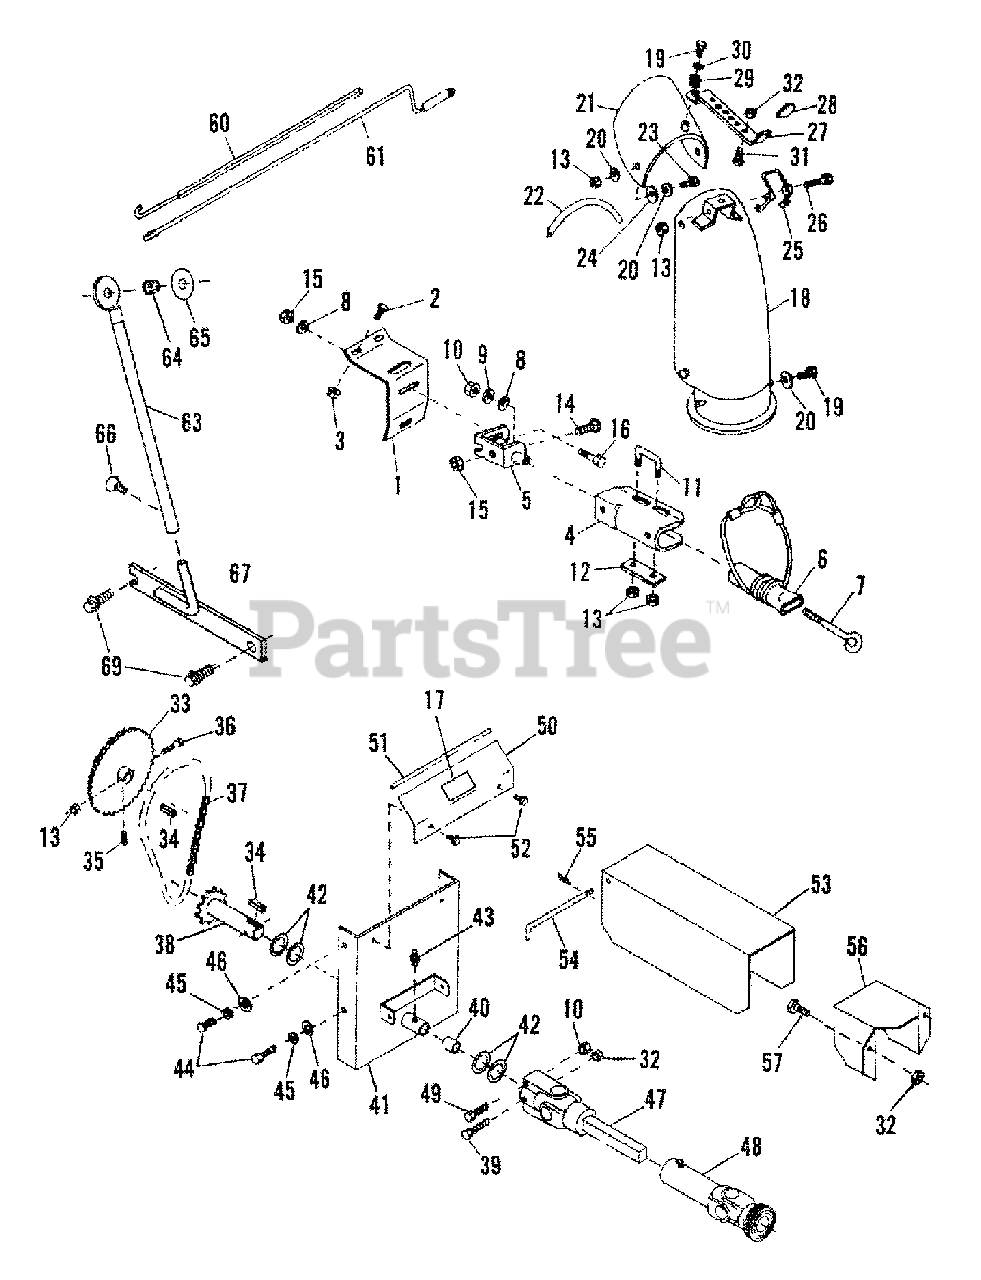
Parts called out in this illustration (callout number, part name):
1	Stack Drive Support Brkt
2	Bolt-Carriage, 5/16-18 x 3/4
3	Nut-Flg lock, 5/16-18
4	Stack Drive Shroud
5	Bracket and Tube Assy
6	Cable, Tube, & Sleeve Assy
7	Eye Bolt
8	Washer - Flat, 7/16
9	Spring Washer 3/8
10	Nut - Lock, 3/8-16
11	Level Wind "U" Bolt
12	Friction Strap
13	Nut-Lock, 3/8-16
14	Bolt - Carriage, 3/8-16 x 3/4
15	Nut - Top Lock - Hex, 3/8-16
16	Bolt - Carriage, 3/8-16 x 1
17	Decal - Warning
18	Elbow
19	Bolt - Hex Hd., 1/4-20 x 1/2
20	Washer - Flat, 1/4
21	Deflector & Decal Assy
22	Seal Trim
23	Bolt - Hex Hd, 1/4-20 x 3/4
24	Washer - Flat, 3/8
25	Deflector Lock Spring
26	Bolt - Hex Hd, 1/4-20 x 1-3/4
27	Deflector Lock Strap
28	Rubber Handle Grip
29	Rubber Grommet
30	Washer - Flat, 1/4
31	Bolt - Hex Hd 3/8-16 x 3/4
32	Nut - Top Lock, 5/16-18
33	Sprocket and Hub Assy
34	Key - Square, 1/4 x 1
35	Setscrew - Sq. Hd, 5/16-18 x 1/2
36	Bolt - Hex Hd, 1/4-20 x 2
37	Drive Chain
38	Jackshaft Assy
39	Bolt - Hex Hd, 5/16-18 x 2
40	Roller Bearing
41	Jackshaft Housing Assy
42	Washer - Flat
43	Grease Fitting
44	Bolt - Hex Hd, 3/8-16 x 1
45	Washer - Lock, 3/8
46	Flat Washer, 3/8
47	PTO Shaft Assy - Male
48	PTO Shaft Assy - Quick disc.
49	Bolt - Hex Hd, 3/8-16 x 1-3/4
50	Chain Guard
51	Molding
52	Screw - Self Tap, 5/16-18 x 1/2
53	PTO Guard
55	Hitch Pin
56	PTO Cover
57	Bolt - 5/16-18 x 1" Hex Head
60	Crank Rod Extension
61	Crank Rod
63	Crank Rod Support
64	Crank Rod Guide Bushing
65	Crank Rod Decal
66	Thumb Screw
67	Crank Rod Support Anchor
69	Bolt - Flange Head 3/8-16 x 1"
